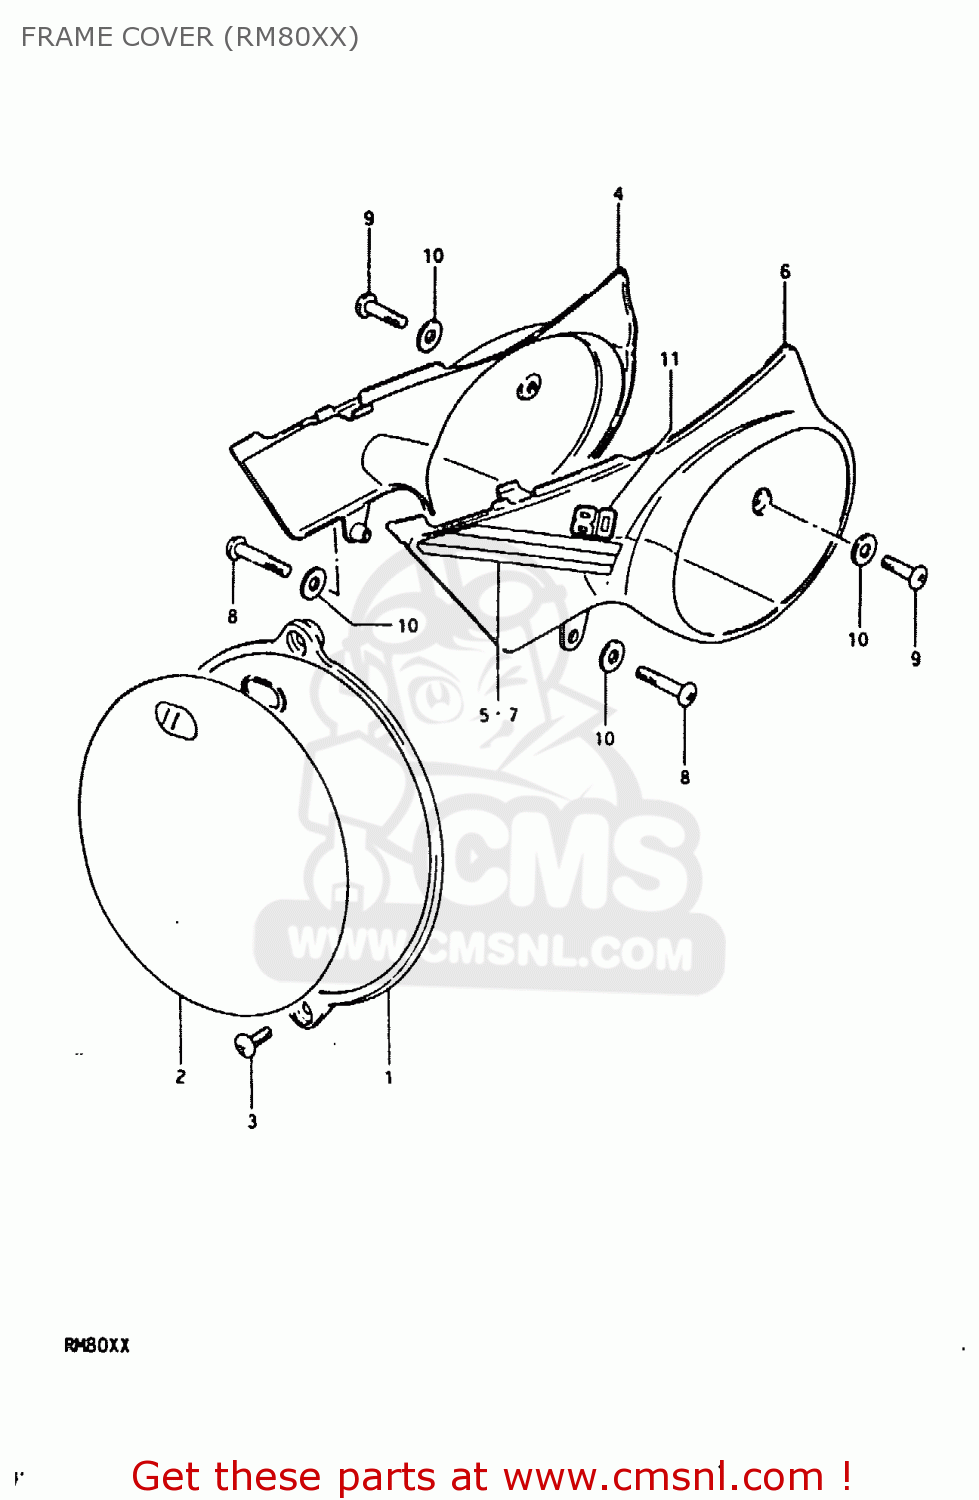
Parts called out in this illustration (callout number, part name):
1	PLATE,NUMBER,FRONT
2	EMBLEM,FRONT NUMBER PLATE
3	SCREW
4	COVER,FRAME,R(YELLOW)
5	TAPE, STRIPING RH
6	COVER,FRAME,LEFT
7	TAPE, STRIPING LH
8	SCREW, NO. 1
9	SCREW
10	WASHER
11	EMBLEM
